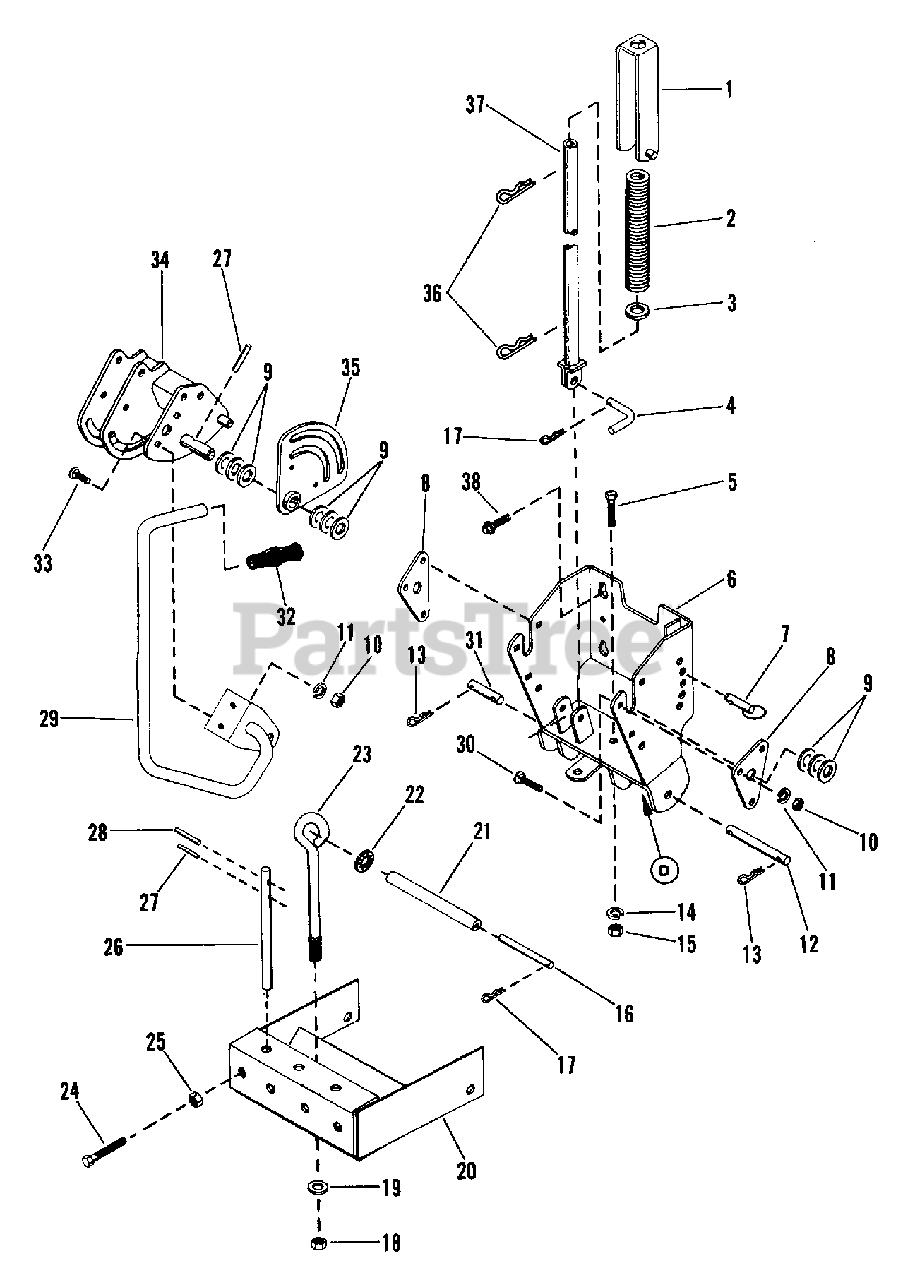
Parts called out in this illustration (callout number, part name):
1	RETAINER
2	SG-COMP .307X1.34X9.88 WLD ??
3	WSHR-FL-STL 1.140X1.718X.134PL
5	BLT-HEX .50-13X1.25 PL GR5
6	LIFT FRAME
7	HITCH PIN
8	BEARING PLATE
9	WSHR-FL-STL 1.062X1.344X.032PL
10	NUT-HEX .375-16
11	WSHR-LK .375X.115 HVY PL
12	PIN
13	PIN-HAIR EXT .12X.31X2.37 PL
14	WSHR-LK .500X.151 HVY PL
15	NUT .50-13 PL
17	PIN-HAIR INT .09X.188 PL
18	NUT-LK-CTR .50-13
19	WSHR-FL-STL .565X1.375X.125 PL
20	DRAW BAR
21	SPACER .632X.844X4.156
22	NUT-PUSH .83 TINRMAN
23	EYE BOLT
24	BLT-HEX .50-13X2.50 PL GR2 FTH
25	NUT-JAM .50-13 PL
27	PIN-ROLL .188X1.50
28	PIN-ROLL .250X3.00
29	LIFT HANDLE
30	BLT-RDHDSQNK .38-16X1.25 GR5PL
32	GRIP
33	BLT-RDHDSQNK .38-16X1.0 GR5PL
34	LIFT CRANK
35	QUADRANT
36	PIN-HAIR INT .17X.68X3.50 PL
37	SPRING GUIDE
38	SCREW - FLG WIZ LOCK HH PL
